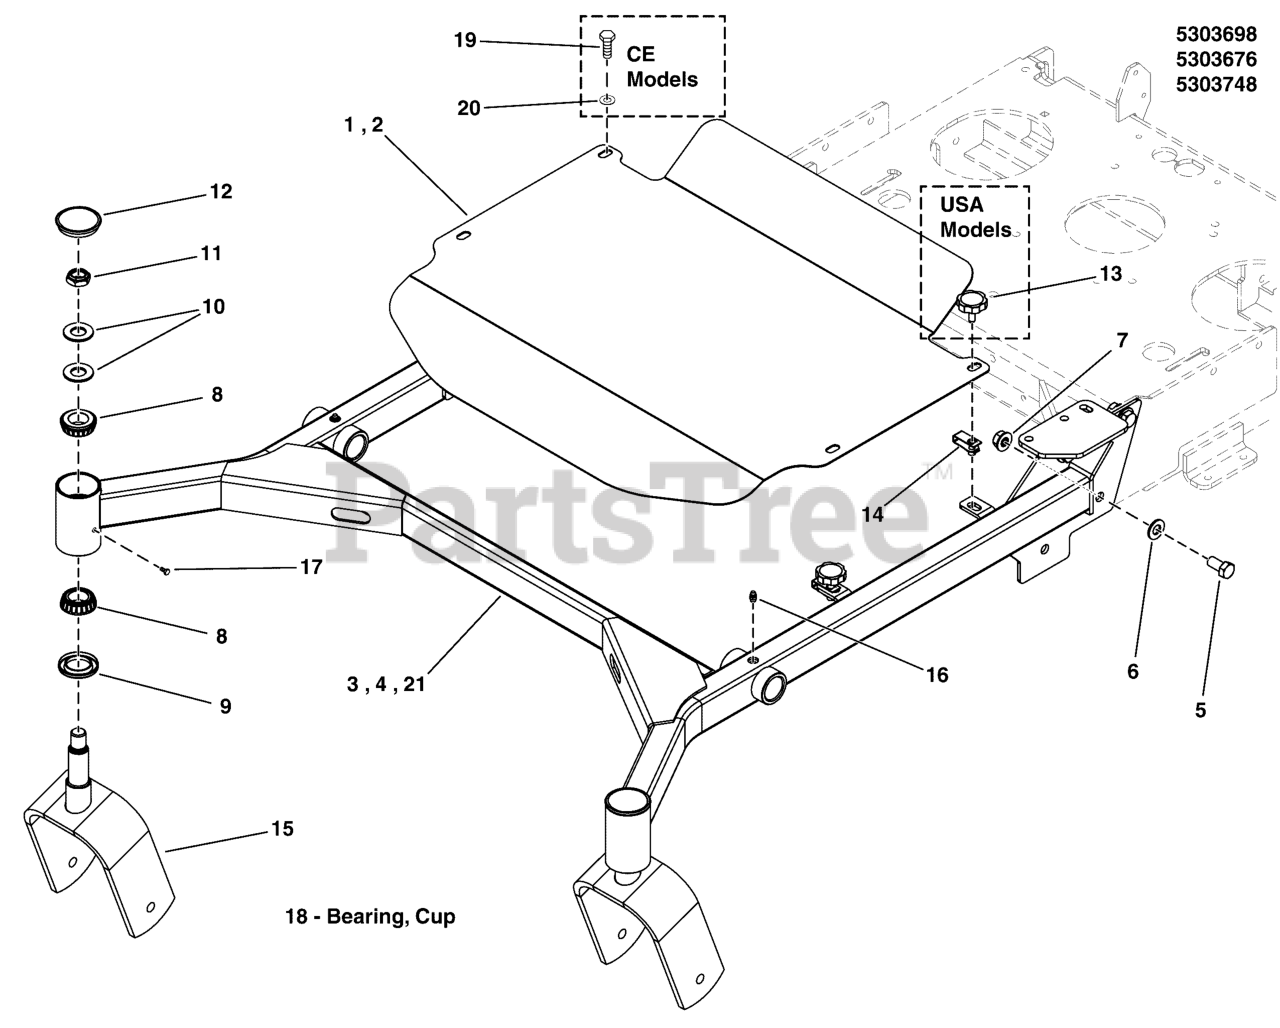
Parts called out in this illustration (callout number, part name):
1	GUARD, WALK, FRONT FRAME, 48-52 - RED
2	GUARD, WALK, FRONT FRAME, 61 - RED
3	WELD, FRONT FRAME, WALK-48-52 - RED
4	WELD, FRONT FRAME, W45, 61 - RED
5	BOLT, 1/2-13 X 1-1/4 GD5 CZ
6	WASHER, 1/2 SAE
7	NUT, Hex Flange, Nylock, 1/2-13
8	BEARING, TAPERED ROLLER, 1
9	SEAL, GREASE
10	WASHER, BELLEVILLE - 1.500 X .755
11	NUT, 3/4-16, HEX JAM NYLON LOCK
12	CAP, GREASE, LOW PROFILE
13	KNOB, 5/16-18 X 1.00, ROSETTE, BLK
14	BODY CLIP, 5/16-18-7GA MATERIAL
15	WELD, FRONT CASTER YOKES - RED
16	GREASE FITTING, 1/4-28 STRAIGHT
17	BOLT, 1/4-28 X 1/2, GD5 YZ
18	BEARING, CUP
19	BOLT, 5/16-18 X 1 GD5 CZ
20	WASHER, 5/16" SAE
21	WELD, FRONT FRAME, W45, 478/52 - RED
